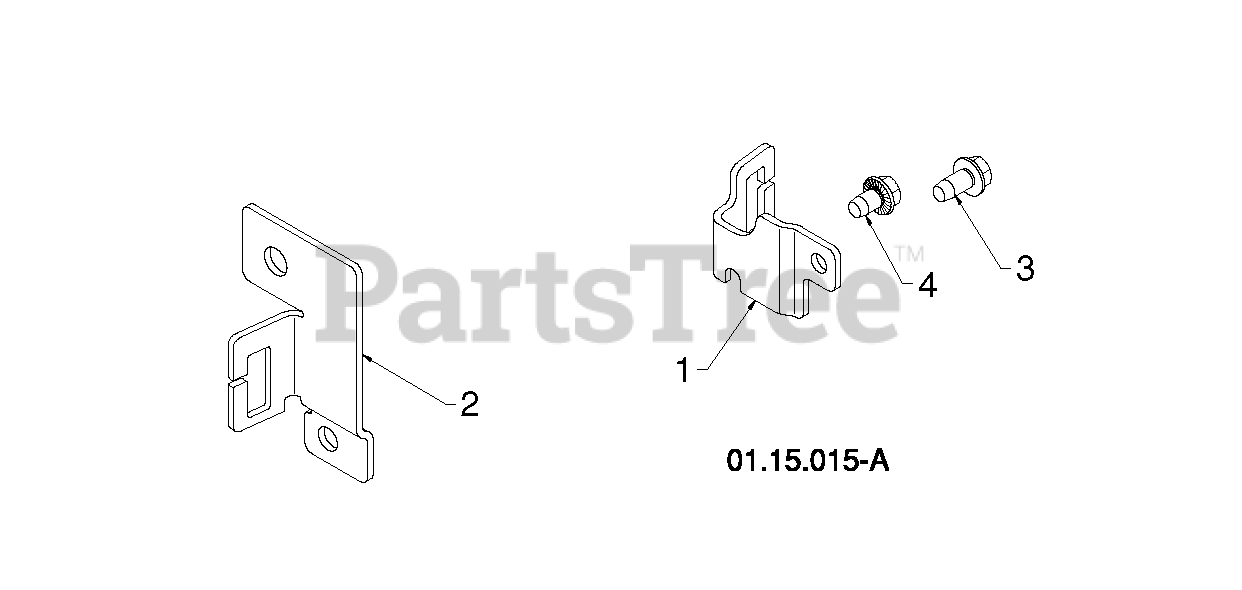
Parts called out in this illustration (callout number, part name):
1	BRACKET. STEER.CABLE.LH
2	BRACKET.STEER.CABLE.RH
3	SCREW
4	SCREW 1/4X20
